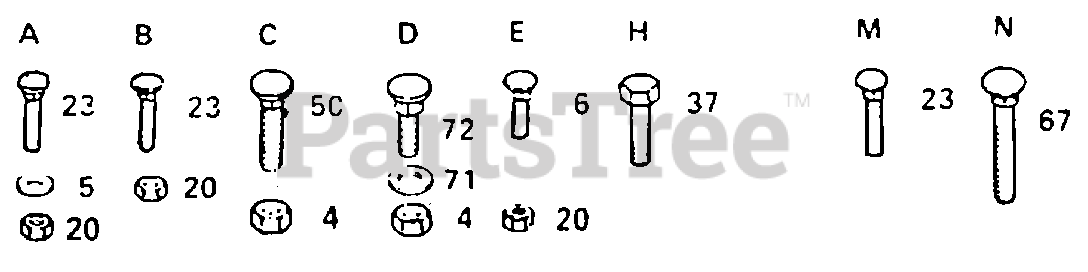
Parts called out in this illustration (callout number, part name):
5	WASHER M
6	BOLT
23	BOLT
37	SCREW
50	BOLT
67	BOLT.3/8-14X1.25
71	WASHER
72	BOLT
